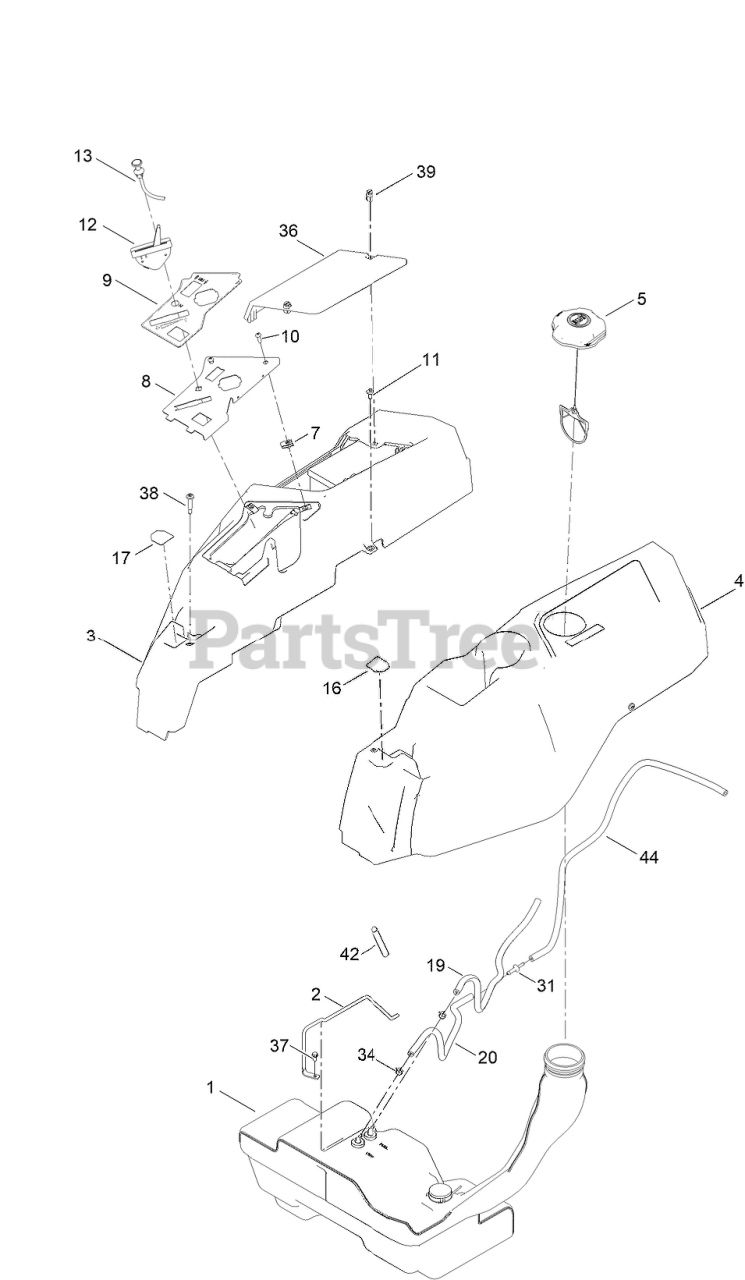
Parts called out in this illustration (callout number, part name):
1	FUEL TANK ASM
2	ROD-HOLD DOWN
3	POD-RH
4	POD-LH
5	CAP-FUEL, RATCHETING
8	PANEL-CONTROL
9	DECAL-PANEL, CONTROL
10	SCREW-PRH
11	SCREW-SHOULDER
12	CABLE-THROTTLE
13	CABLE-CHOKE
16	DECAL-LEVER, CONTROL (LH)
17	DECAL-LEVER, CONTROL (RH)
19	HOSE-FUEL
20	HOSE-FUEL
31	ADAPTOR-ORIFICE
34	CLAMP-HOSE
36	COVER-BATTERY
37	SCREW-HWH
38	SCREW-SHOULDER
39	FASTENER
42	SLEEVE-FUEL LINE PROTECTOR
44	HOSE-FUEL
